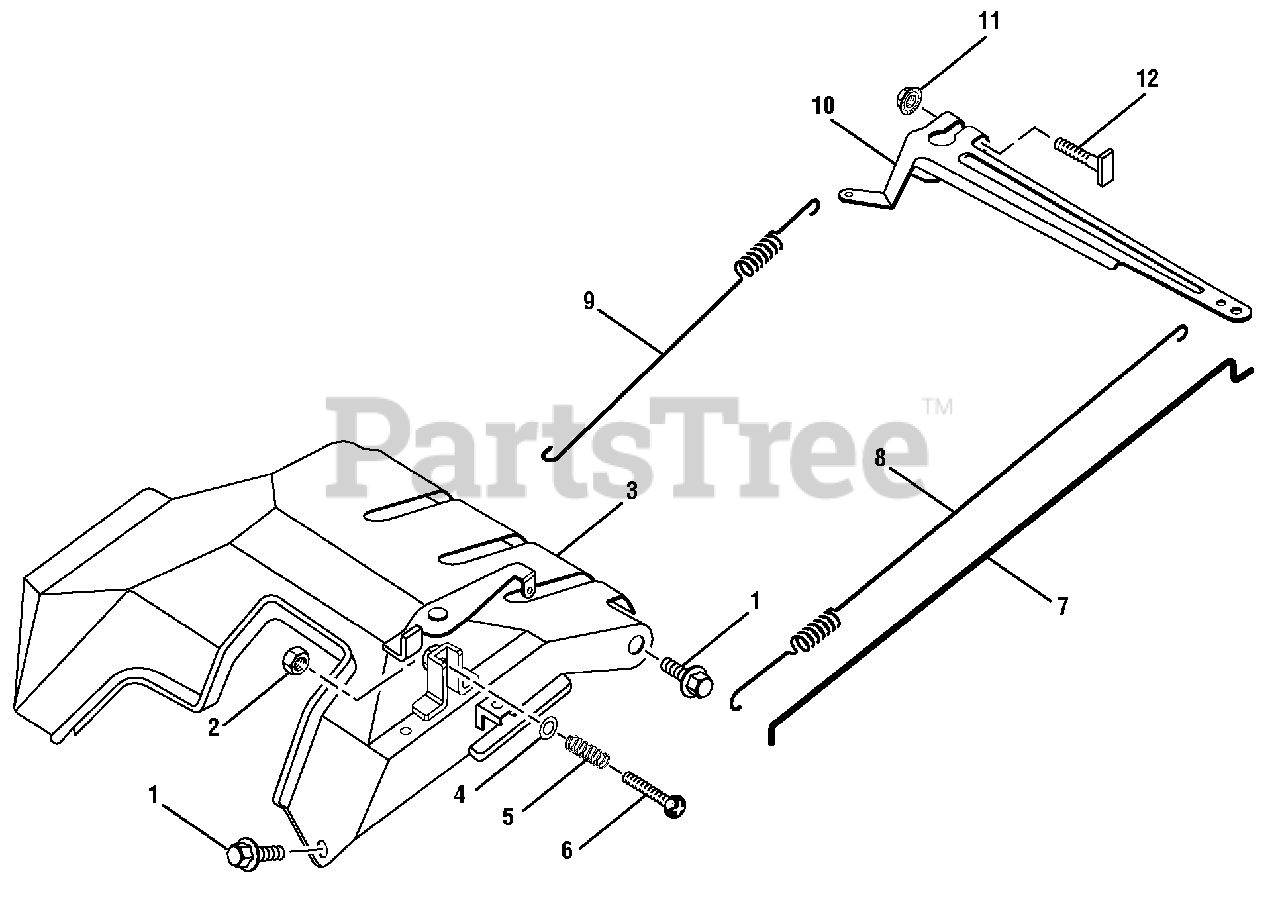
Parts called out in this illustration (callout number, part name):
1	Bolt (M6 x 12, Flange)
2	Hex Nut (M5)
3	Engine Cover
4	Washer (M5)
6	Screw (M5 x 40)
8	Regulator Spring (Fine)
9	Regulator Spring (Back)
10	Regulating Arm
11	Flange Nut (M6)
12	Lock Bolt
